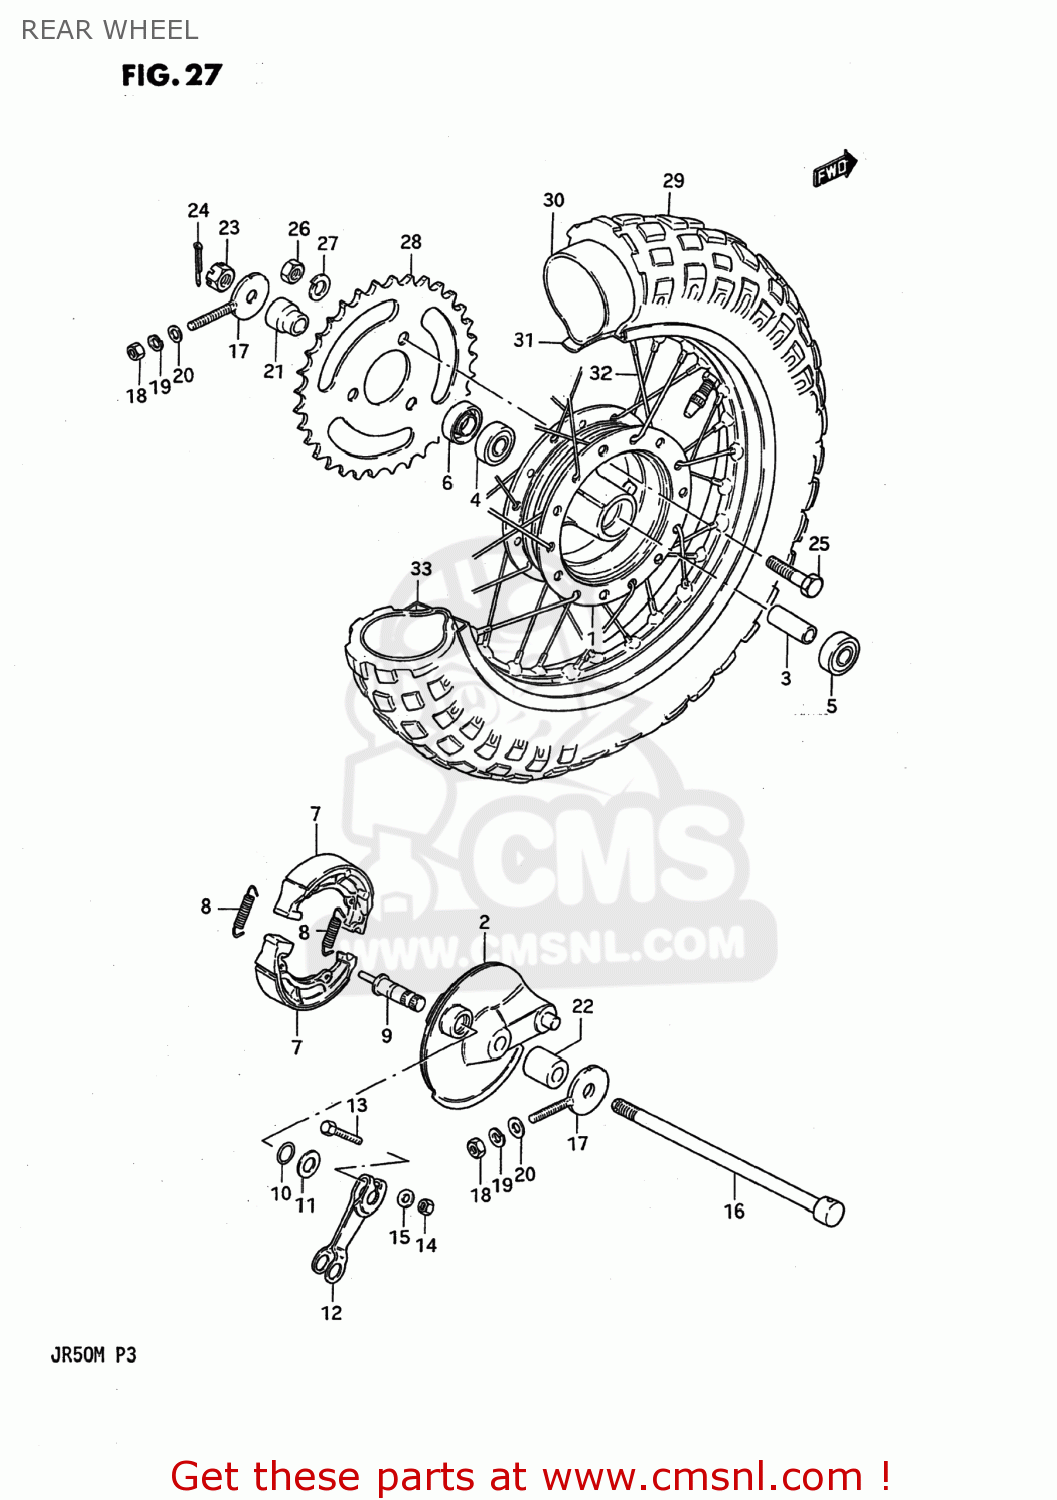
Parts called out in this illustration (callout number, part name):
1	HUB,RR WHEEL
2	PANEL,RR BRAKE ANCHOR
3	SPACER (10.2X16X55)
4	BALL BEARING K
5	BEARING
6	SEAL,OIL(15X27X6)
7	SHOE,BRAKE
8	SPRING(L:34)
9	CAM,FRONT BRAKE
10	O RING(D:2.4,ID:9.8)
11	WASHER (10.5X18X1)
12	LEVER,RR BRAKE CAM
13	BOLT
14	NUT
15	WASHER
16	AXLE,RR
17	ADJUSTER,CHAIN
18	NUT 6MM
19	WASHER,LOCK
20	WASHER
21	SPACER,RR AXLE,L
22	SPACER,RR AXLE,R
23	NUT
24	PIN 20X20
25	BOLT
26	NUT
27	LOCK WASHER
28	SPROCKET,RR
29	TIRE
30	TUBE,INNER
31	PROTECTOR,INNER TUBE
32	SPOKE SET,RR
33	RIM,WHEEL
